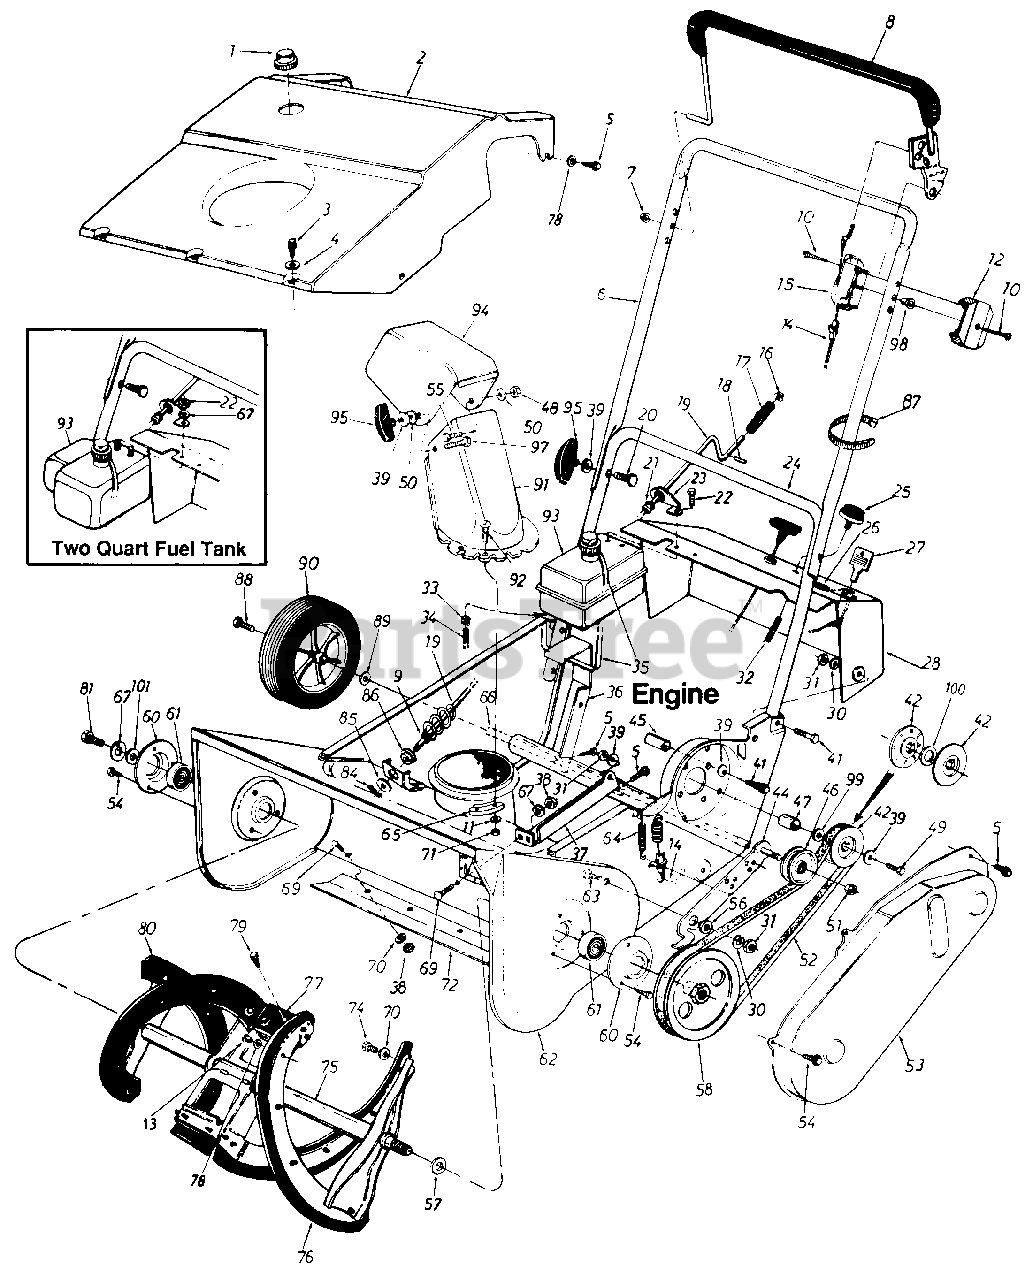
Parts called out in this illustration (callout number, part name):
1	Gas Tank Cap
2	21" Shroud
3	Hex B-Tap Scr. #10 x .38"
4	Spr.-Wash. .206" 1 .D. x .448"
5	Hex L-Wash. Hd. AB-Tap 1/4 x .62" Lg.
8	Control Handle Ass'y.-L.H.
9	Fl-Wash. .385" I.D. x .62"
10	Truss Mach. Hi-B 0 Tap Scr. #12 x 1.5" Lg.
11	Fl-Wash. .281" I.D. x .5" O.D.
12	Control Panel Half
13	Pop Rivet .188" Dia.
14	Clutch Cable 35" Lg.
15	Control Panel Half
16	Push Cap 3/8" Rod
17	Knob-3/8" Dia. Hole
18	Roll Pin 1/8" Dia. x .63" Lg.
19	Chute Crank Ass'y.
20	Curved Carriage Bolt 5/16-18 x 1.75" Lg.
21	Chute Crank Grommet
22	Hex AB-Tap Scr. 1/4 x .75" Lg.
22	Hex Nut 1/4-20 Thd.
23	Upper Chute Crank Brkt.
24	Lower Handle
26	Plastic Plug
27	Plastic Key
28	Dash Panel Ass'y.
30	L-Wash. 5/16" I.D.
31	Hex Nut 5/16-18 Thd.
32	Primer Hose-11" Lg.
33	Hose Clamp-1/2" Dia.
34	Gas Line-12" Lg.
35	Cable Tie-17.75" Lg.
36	Engine Support Brkt.
37	Engine Support
38	Hex Jam Nut 1/4-20 Thd.
39	Bell-Wash. .345" I.D. x .88"
41	Hex Bolt 5/16-18 x 1.5" Lg.
42	3/8" "V"-Pulley Half .625" I.D. x 6.0" O.D.
44	Idler Brake Brkt. Ass'y.
45	Spacer .325" I.D. x .625" O.D. x .875"
46	Fl-ldler w/Flanges 2.12" O.D.
47	Spacer .635" I.D. x .89" O.D. x .57"
48	Hex L-Nut 5/16-18 Thd.
49	Hex Bolt 5/16-24 x .75" Lg.
50	Fl-Wash. .344" I.D. x 1.25"
51	Hex Patch L-Nut 3/8-24 Thd.
52	V-Belt
54	Hex B-Tap Scr. 1/4" x .38" Lg.
55	Carriage Bolt 5/16-18 x .75"
56	Shld. Spacer .50" Dia. x .27"
57	Fl-Wash. .510" I.D. x 1.0" O.D.
58	3/8" "V"-Pulley 1/2-20 L.H. x 6"
58	1/2" "V"-Pulley 1/2-20 L.H. x 6"
60	Bearing Cup
61	Ball Brg. .669" I.D. x 1.574"
64	Extension Spring 1.12" Lg.
65	Chute Flange Keeper
66	Wheel Axle 1/2" O.D. x 20.6" Lg.
67	L-Wash. 1/4" I.D.
69	Carriage Bolt 1/4-20 x .50"*
70	Fl-Wash. .281" I.D. x .73"
71	Hex L-Nut 1/4-20 Thd.
72	Shave Plate
74	Hex Wash. B-Tap Scr. 1/4 x .62"
75	Auger Ass'y. 21"
76	Rubber Spiral-L.H.
77	Rubber Paddle
78	Fl-Wash. .218" I.D. x .62"
79	Hex Wash. B-Tap Scr. #10 x .62" Lg.
80	Rubber Spiral-R.H.
81	Hex Wash. TT-Tap Cl-Scr. 1/4-20 x .75" Lg.
84	Cotter Pin 3/32" Dia. x .75"
85	Fl-Wash. .406" I.D. x 1.25"
86	Hex Bushing .385" I.D.
87	Cable Tie
88	Hex Tap Scr. 3/8-24 x .5" Lg.
89	Fl-Wash. .510" I.D. x .75"
90	Wheel & Tire Ass'y. 7" x 1.5"
91	Lower Chute
92	Truss Mach. Scr. 1/4-20 x .75"
93	Fuel Tank-One Quart
94	Upper Chute
95	Knob Handle.Ass'y.
97	Carriage Bolt 5/1 6-1 8 x 1"*
98	Control Disc Pin
99	Fl-Wash. .635" I.D. x 1.04" O.D.
100	Fl-Wash. .635" I.D. x .93" O.D.
101	Fl-Wash. .25" I.D. x .93"
